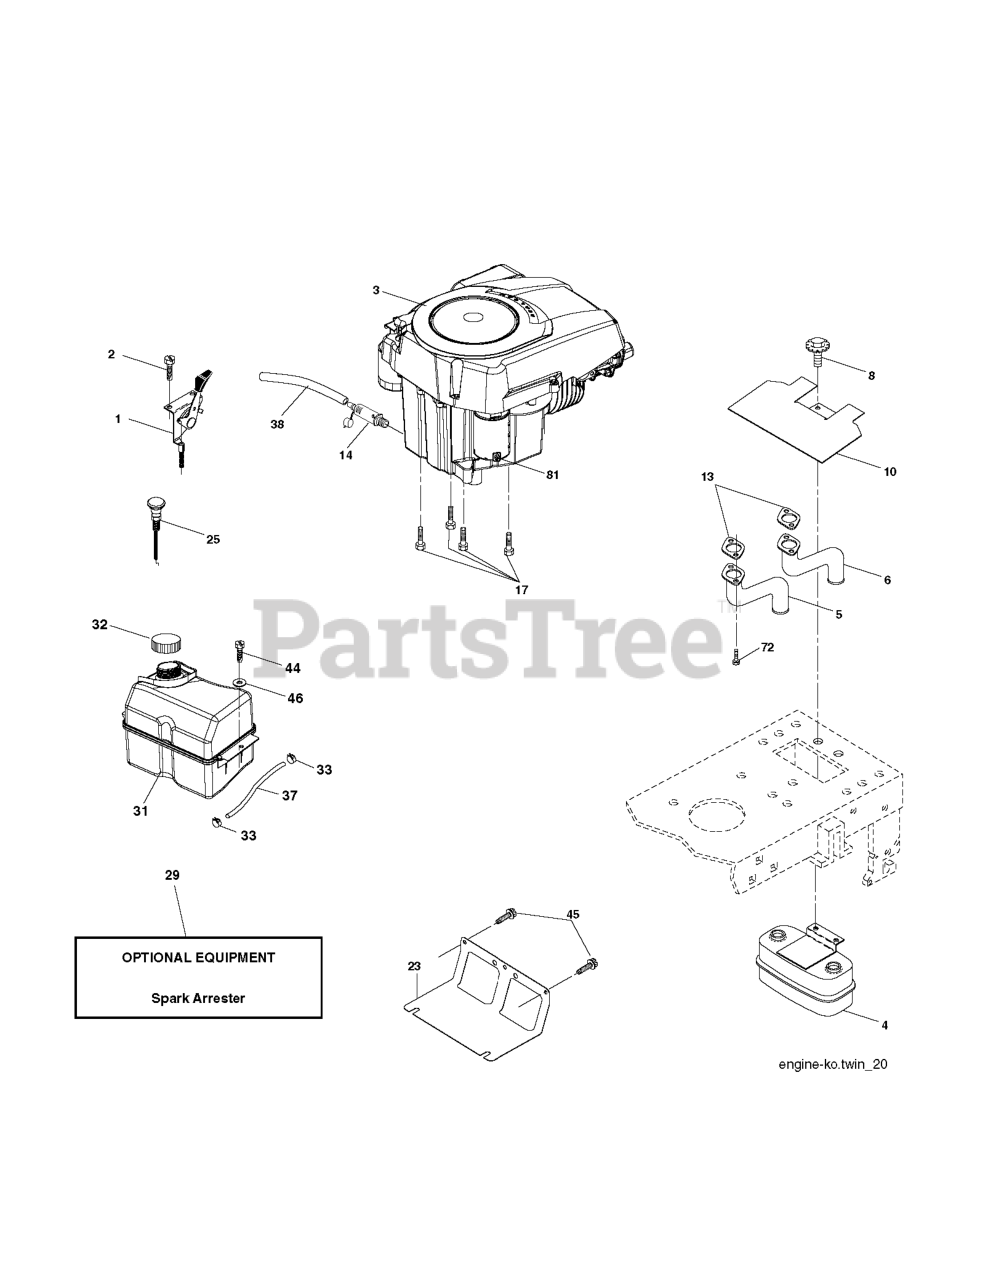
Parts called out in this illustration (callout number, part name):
1	THROTTLE CONTROL
2	SCREW
4	MUFFLER.TWIN.CYL.LOW.TONE
5	RP.PIPE-EXHAUST LH
6	RP.PIPE-EXHAUST RH
8	BOLT.5/16-18UNCX3/4 W/SEMS.BLK
10	RP SHIELD HEAT MUFFLER
13	GASKET.EXHAUST.KOHL.CV18-CV26
14	TUBE, DRAIN OIL ASM.
17	SCREW 3/8-16X1
23	SHIELD.BROWNING.DBR.GUARD
25	CONTROL, CHOKE
29	KIT.SPARK ARRESTOR 794945 B&S
31	TANK.ASM.FUEL.FR.2.5GA.
32	FUEL CAP
33	HOSE CLAMP
37	LINE.FUEL.20
38	PLUG DRAIN OIL EASY
44	SCREW HEXWSHR 1/4-20X3/4
45	SCREW, 3/8-16X3/4
72	SCREW.SOCKET HD.5/16-1
81	NUT
